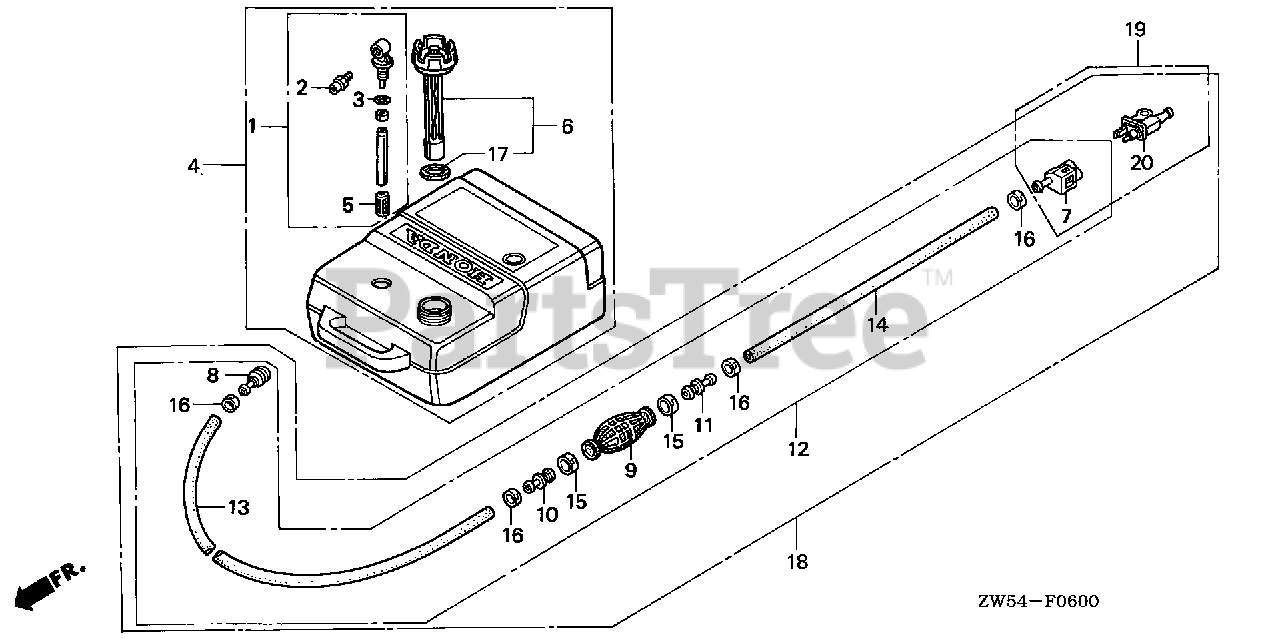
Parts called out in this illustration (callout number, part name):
1	JOINT ASSY., FUEL
2	FITTING, QUICK DISCONNECT
3	O-RING
4	TANK ASSY., FUEL
5	FILTER, FUEL
6	CAP, FUEL FILLER
7	CONNECTOR ASSY., FUEL (A)
8	CONNECTOR, FUEL
9	BULB, PRIMER
10	VALVE, IN.
11	VALVE, OUTLET
12	TUBE ASSY., FUEL
13	TUBE, FUEL LONG (7.3X2000)
14	TUBE, FUEL SHORT (6.3X500)
15	BAND, TUBE CLIP (20MM)
16	BAND, TUBE CLIP (12.5MM)
17	GASKET, FUEL CAP
18	CONNECTOR SET, FUEL TUBE
19	CONNECTOR SET, FUEL
20	CONNECTOR ASSY., FUEL (B)
